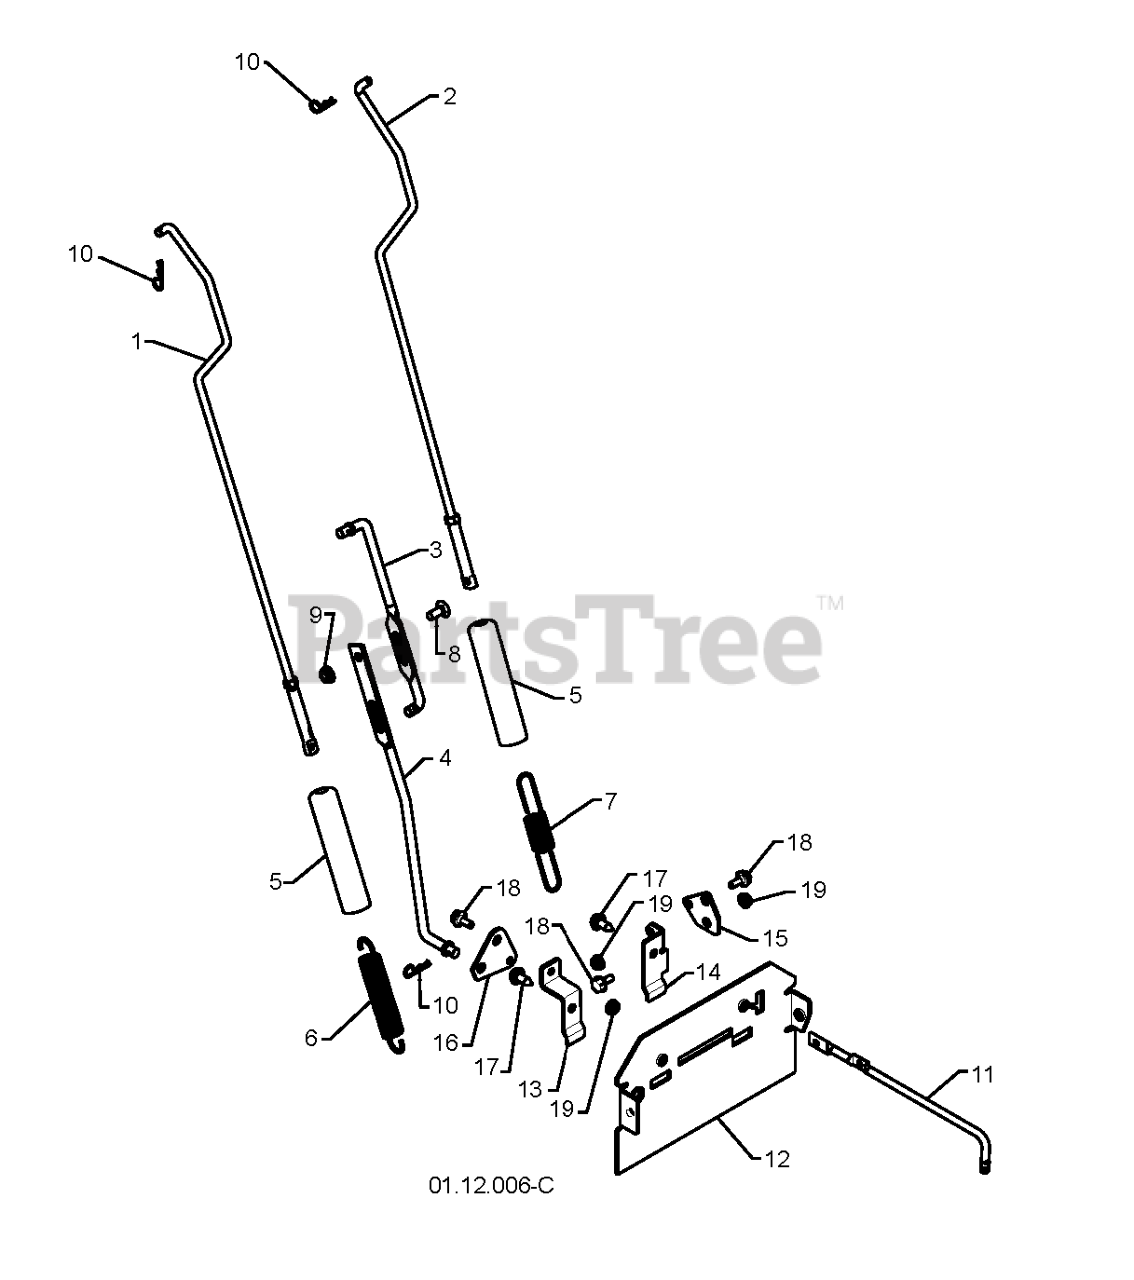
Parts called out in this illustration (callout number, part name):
1	ROD.ASM.IMPELLER
2	ROD.ASM.TRACTION
3	ROD, UPPER SPEED CONTROL
4	ROD, LOWER SPEED CONTROL.SNOW
5	SLEEVE, SPRING
6	SPRING, AUGER CONTROL
7	SPRING, TRACTION DRIVE
8	BOLT
9	NUT.FLANGE.5/16
10	SPRING RETAINER
11	ROD.CLUTCH.YELLOW.ZINC(VT)
12	PLATE.REAR.SNOW.PNT.ORANGE
13	BRACKET.SHIFTER.PLATE.BZP
14	BRACKET.CLUTCH.PLATE.BZP
15	PLATE.CLUTCH.BZP
16	PLATE.SHIFTER.BZP
17	BOLT.HEX.HD.WASHER.5/16-18X.75
18	BOLT.SHOULDER.3/X.25
19	NUT.HEX.FLANGE.1/4
